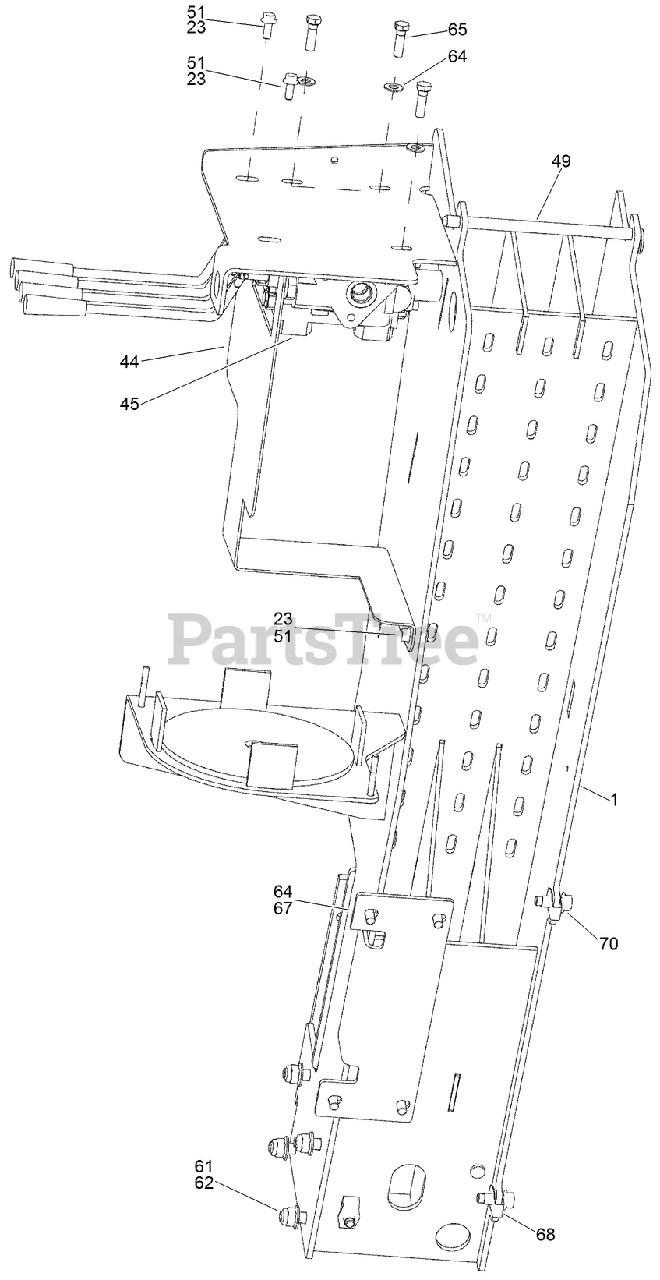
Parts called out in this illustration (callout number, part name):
1	ASSEMBLY - Front Rod Box
23	SCREW, METRIC FLANGE w/BODY - M8 x 20
44	PLATE - Guard
45	4 SPOOL HYD VALVE ASM
51	NUT-TORQUE, PREVAILING
61	NUT-HHF, LOCK
62	SCREW-HFH
64	WASHER-0.406 x 0.812 x 0.065 in CST ZND
65	BOLT
67	SCREW-HH
70	SCREW-HH
